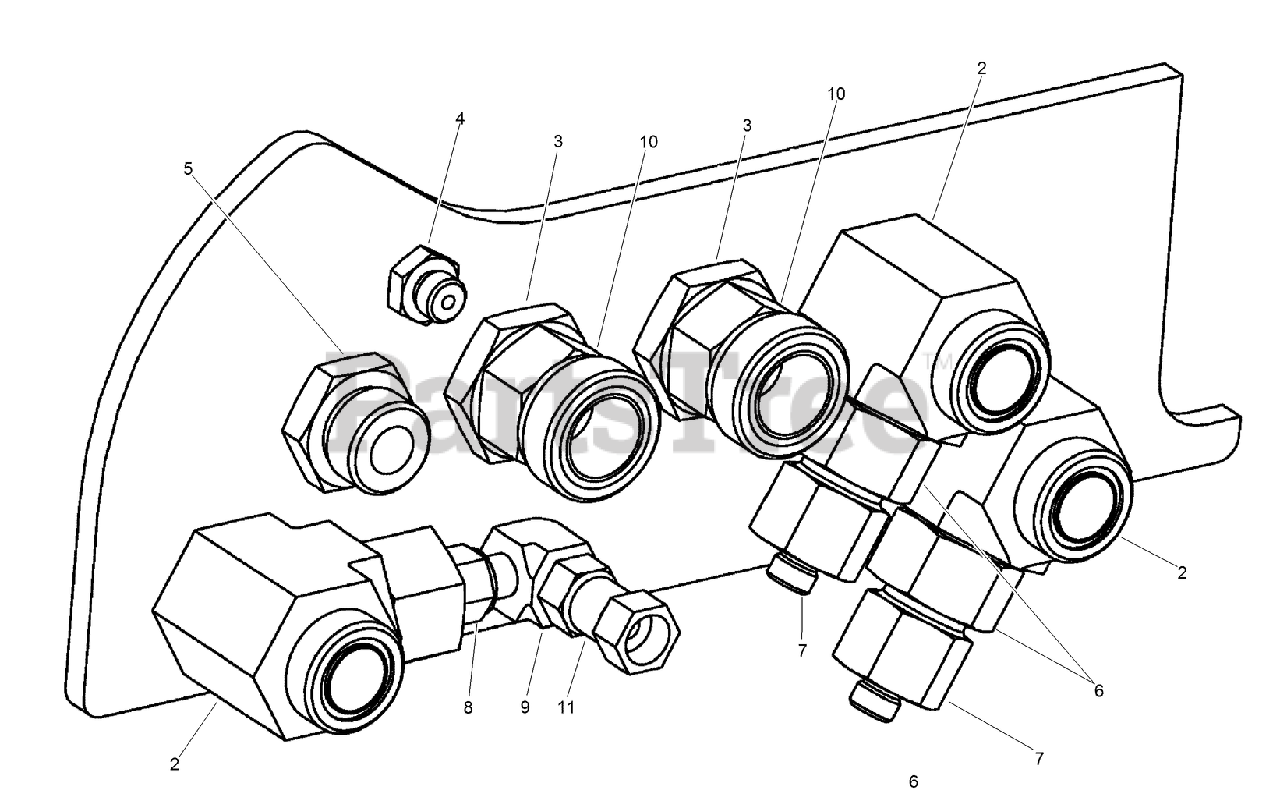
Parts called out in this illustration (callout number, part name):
2	FITTING-TEE, BULKHEAD
3	CONNECTION - Bulkhead, Straight ORFS
4	FITTING-STRAIGHT
5	FITTING-STRAIGHT
6	FITTING-REDUCER
7	FITTING-REDUCER
8	FITTING-REDUCER
9	CONNECTION - 90 Deg, -6 ORFS / -6 ORFS
10	FITTING-REDUCER
11	CONNECTION - Female Straight, -6 SAE FEM / -6 ORFS FEM
